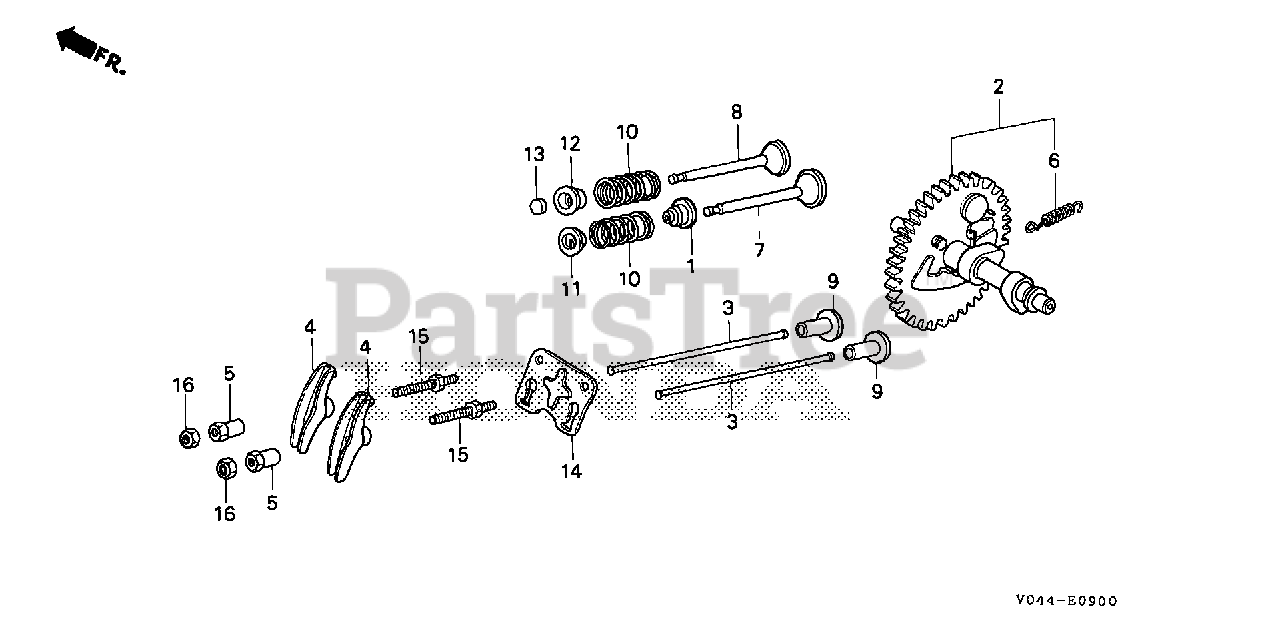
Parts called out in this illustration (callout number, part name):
1	SEAL, VALVE STEM
2	CAMSHAFT ASSY.
3	ROD, PUSH
4	ARM, VALVE ROCKER
5	PIVOT, ROCKER ARM
6	SPRING, WEIGHT RETURN
7	VALVE, IN.
8	VALVE, EX.
9	LIFTER, VALVE
10	SPRING, VALVE
11	RETAINER, IN. VALVE SPRING
11	RETAINER, VALVE SPRING (EXHAUST SIDE)
12	RETAINER, EX. VALVE SPRING
13	ROTATOR, VALVE
14	PLATE, PUSH ROD GUIDE
15	BOLT, PIVOT (8MM)
16	NUT, PIVOT ADJ.
